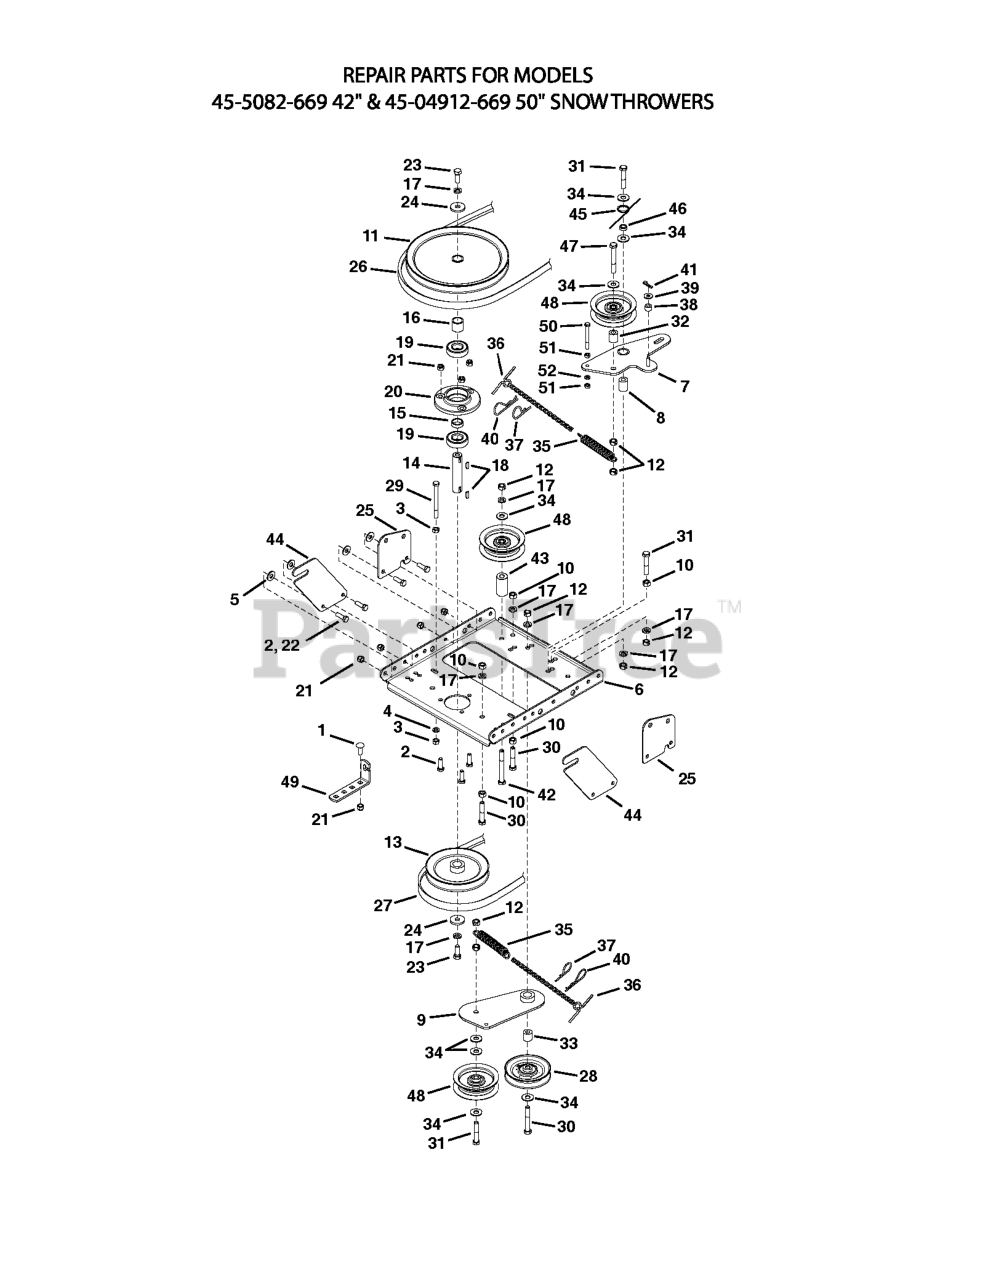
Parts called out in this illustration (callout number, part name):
2	BOLT
4	LOCK WASHER
5	WASHER
7	IDLER ARM 63904
8	SPACER 24286
9	IDLER BRACKET 63762
10	NUT
11	PULLEY 46981
12	NUT 43082
13	PULLEY
17	LOCK WASHER
21	NUT 47810
23	BOLT
26	BELT 48138
26	BELT 46989
28	PULLEY 47044
29	BOLT 47025
31	BOLT
32	SPACER 24571
33	SPACER 24472
35	SPRING 46959
36	CHAIN 46963
38	SPACER 23727
39	WASHER
41	PIN 47134
42	BOLT 46938
43	SPACER 25780
44	BRACKET 25728
45	SPRING 47607
46	BUSHING
47	BOLT 43509
48	PULLEY 48883
49	BRACKET 24558
50	BOLT 49870
